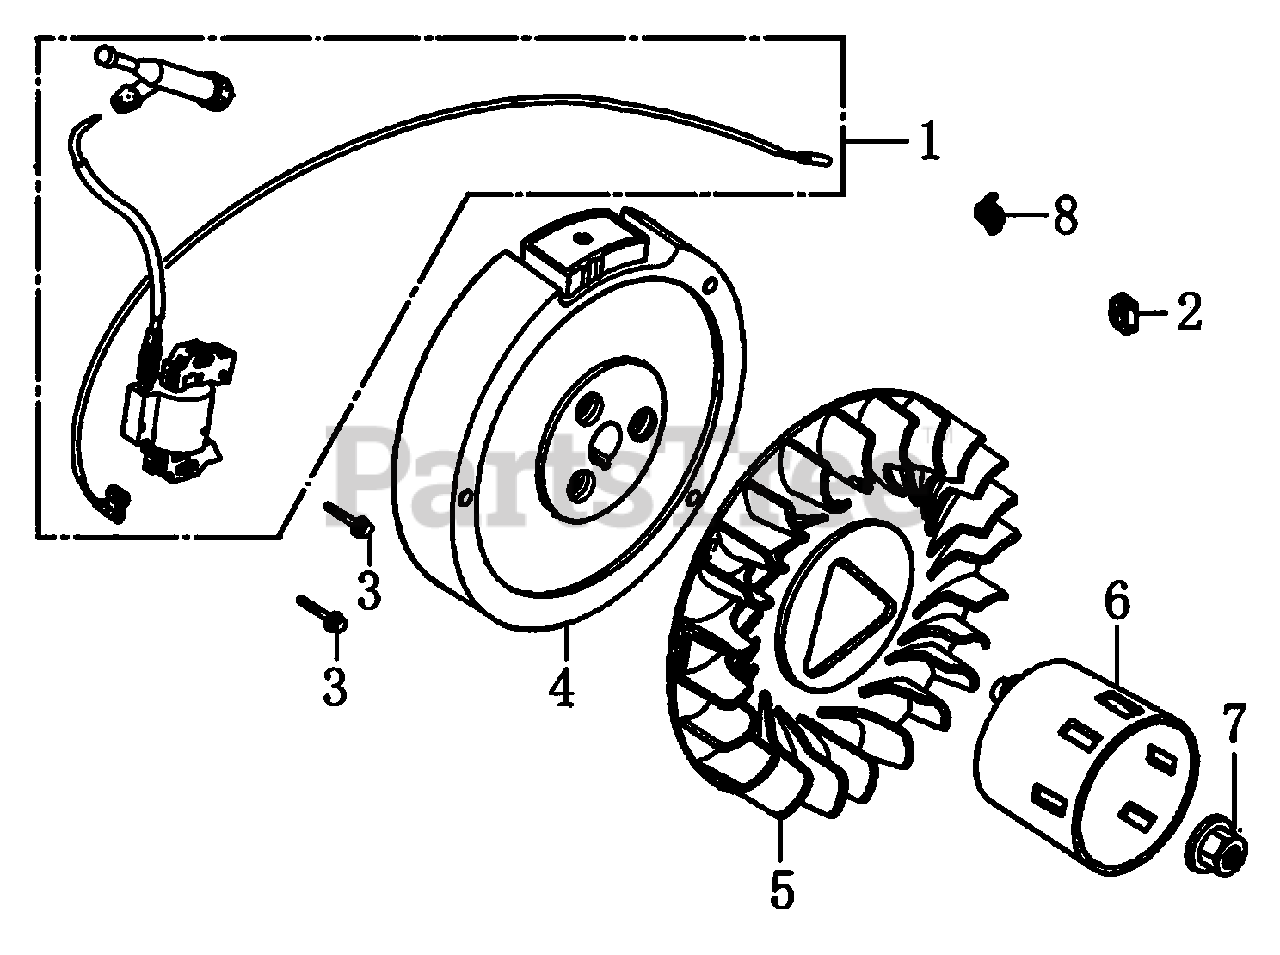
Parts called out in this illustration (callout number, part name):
1	COIL ASSY. , IGNITION
2	GROMMET, CORD
3	BOLT, FLANGE, M6X25
4	FLYWHEEL COMP
5	FAN COOLING
6	PULLEY, STARTER
7	NUT SPECIAL, 16MM
